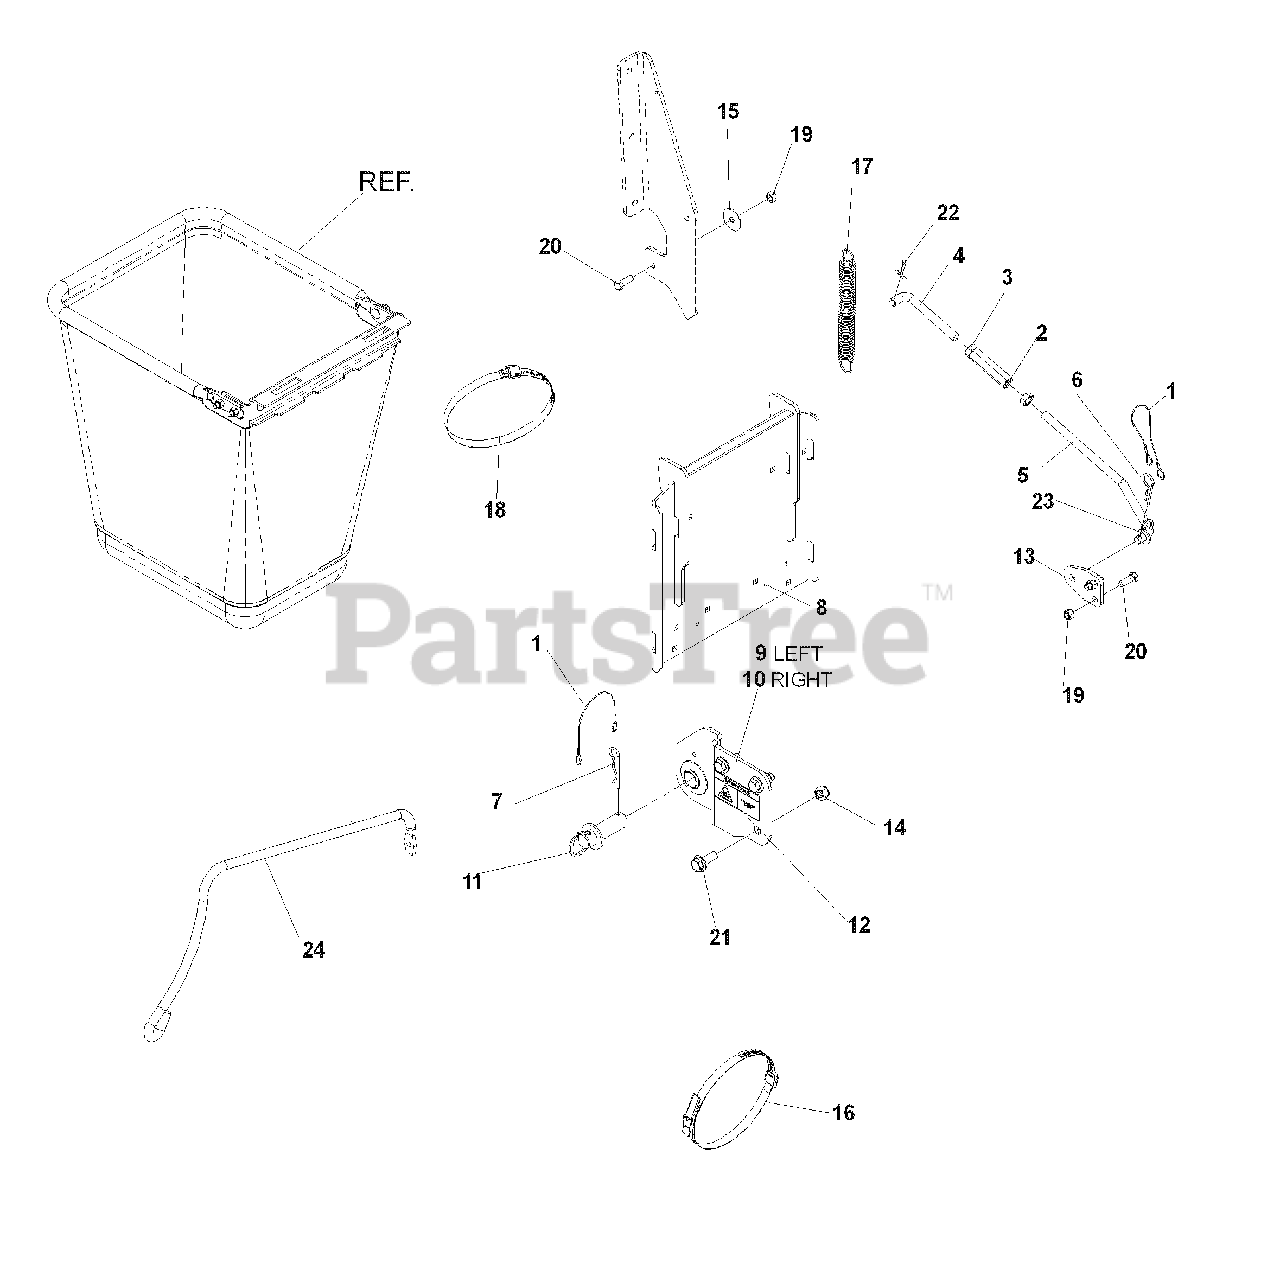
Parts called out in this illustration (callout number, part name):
2	NUT, 1/2-20, JAM
3	TURNBUCKLE, 1/2
4	SUPPORT LINKAGE, LH
5	SUPPORT LINKAGE, MID
6	PIN HAIR, 1/8x2 1/2
8	REAR GUARD, MID
9	HITCH BRACKET, LEFT
10	HITCH BRACKET, RIGHT
12	DECAL, HOT SURFACE
13	SUPPORT BRACKET
14	NUT, 1/2-13, NYLOC
15	WASHER, 39
16	OVERCENTER BAND
18	HOSE CLAMP
19	NUT, 3/8-16, NYLOC
20	HCS, 3/8-16x1 1/2
21	BOLT, 1/2-13x1 1/4, WHIZLK
22	PIN COTTER, 5/32x1 1/4
23	RING, RETAINING, SPEC
24	HOSE SUPPORT
